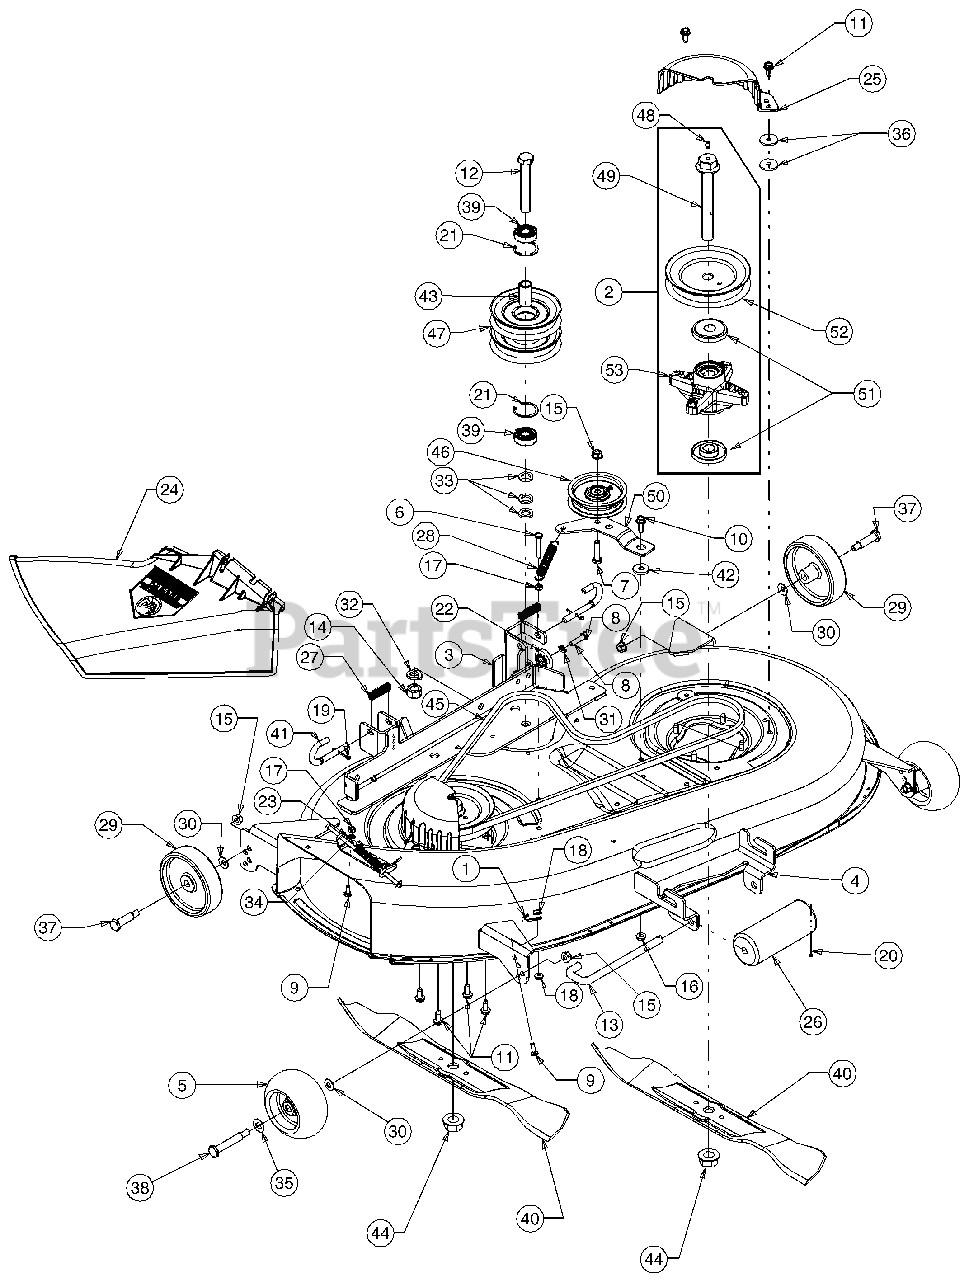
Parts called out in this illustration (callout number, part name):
1	Bracket, Hook, Retainer
5	Wheel, Deck, 5.0 OD w/ Fitting
6	Screw, 1/4-20, 1.75, Gr5
7	Screw, 3/8-16, 1.50, Gr5
8	Screw, 5/16-18, 1.25, Gr5
9	Screw, 1/4-20, .620, Gr5
10	Screw, 5/16-18, .875, Gr5
11	Screw, 5/16-18, .750
12	Screw, 5/8-18, 4.25, Gr5
13	Roller Pin, 1/2" x 7.31 Lg
14	Nut, Hex, 5/8-18, Gr5
15	Nut, Flange Lock, 3/8-16
16	Nut, Flange Lock, 5/16-18, Gr5
17	Nut, Hex, 1/4-20, Gr5
18	Nut, Flange Lock, 1/4-20
19	Pin, Cotter, 1/8 x 1.25
20	Pin, Cotter, 3/32 x 1.25
21	Snap Ring, Internal
22	Adjustment Gear, Deck
23	Nut, Push, .25 ID x .50 OD
24	Chute Assembly, Side Discharge
25	Cover, Belt, 42" Deck
26	Front Roller
27	Spring, Compression, .406 x .531 x 1.75 Lg
28	Spring, Extension .530 OD x 4.74 Lg
29	Wheel Deck 5.0 x 1.38
30	Washer, Bell, .375 x .870 x .063
31	Washer, Lock, 5/16, Regular Duty
32	Washer, Lock, 5/8, Regular Duty
33	Washer, Flat .64 ID x 1.00 OD x .12
34	Washer, Bell, .265 x .75 x .062
35	Washer, Flat, .510 x 1.00 x .060
36	Washer, Flat, .330 x 1.25 x .120
37	Shoulder Screw
38	Shoulder Screw - 1/2 Dia x 2.50 Lg.
39	Bearing, .625 ID x 1.574 OD x .470
40	Blade, 21.20 Lg, 3-in-1
41	Rod, Handle, Deck Release .375 Dia
42	Spacer, Shoulder .625 Dia x .324 Dia
43	Spacer, .635 ID x .88 x 1.72
44	Nut, Flange, 3/4-16
45	Belt, V-Type
46	Pulley, Idler, 3.50 Dia.
47	Pulley, Double, 5.0 x 5.0
48	Fitting, 3/16 Drive Lube
49	Bolt, Spindle, 3/4-16, 4.25
51	Spacer, Spindle, Deck
52	Pulley
53	Spindle Housing Assembly
